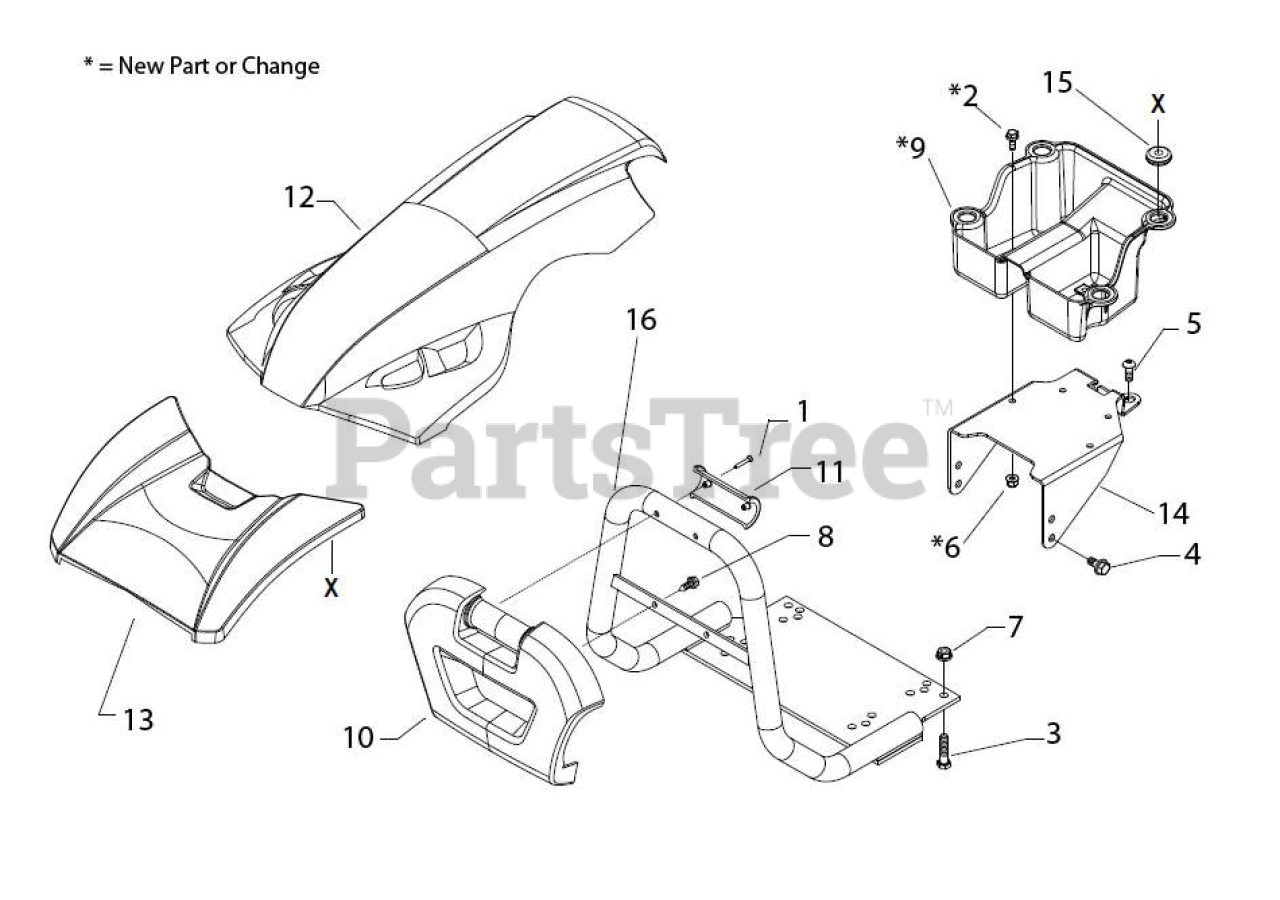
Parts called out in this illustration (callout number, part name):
1	SCREW 3,5X25
2	SCREW TE C/F M6X20
3	SCREW TE M8X40
4	SCREW TE C/F M8X16
5	SCREW TBCEI M10X16
6	SELFLOCK M6
7	SELFLOCK NUT M8
8	RIBBED SCREW 6,3X19
9	SUPPORT TRAY
10	BUMPER GUARD
11	CLAMP
12	COVER HANDLEBAR
13	GUARD, LOWER
14	BRACKET SUPPORT
15	GROMMET
16	BUMPER HONDA GX 340
